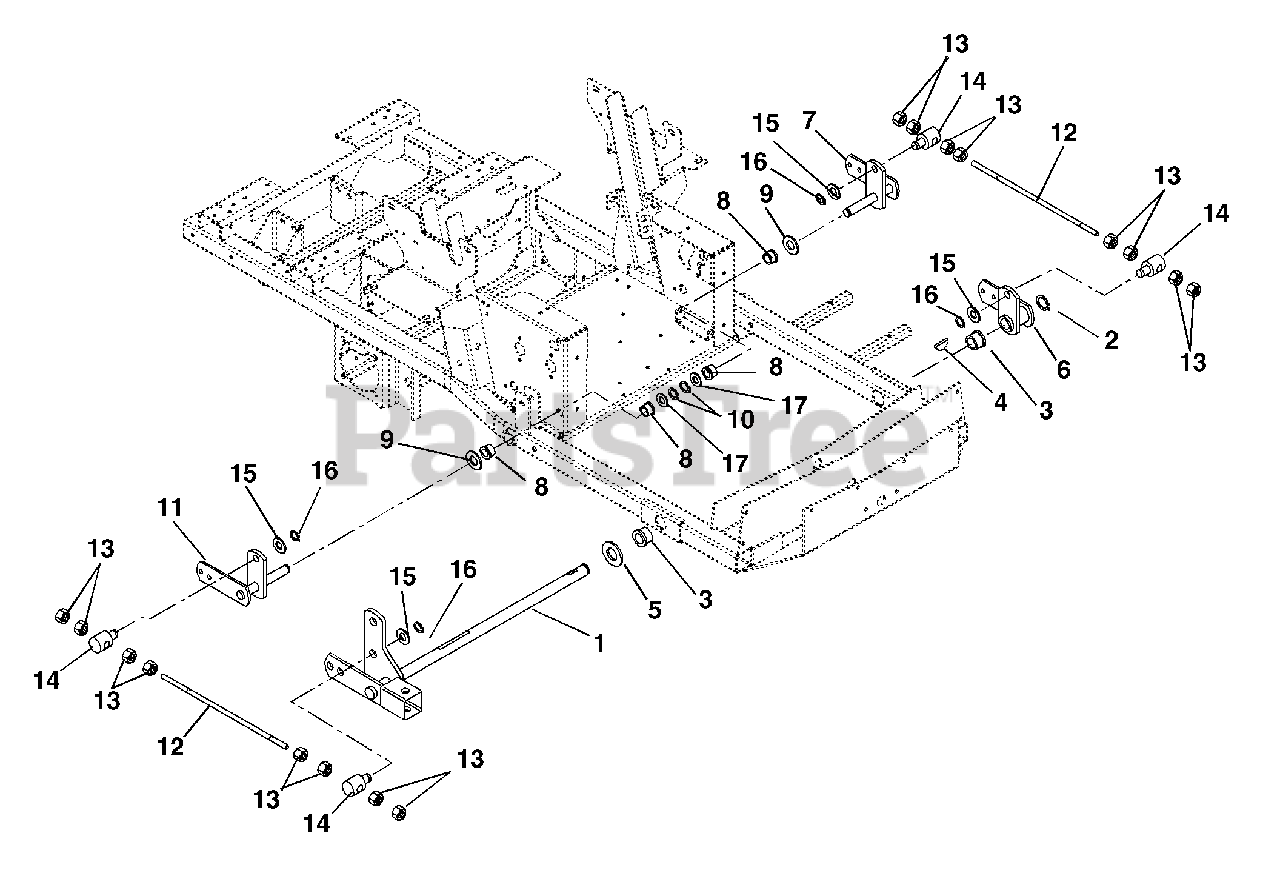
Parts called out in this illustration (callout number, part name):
1	Lift, Mower
2	Ring, Retaining External 1.00 x .078
3	Bushing, Flange Nylon 1.02 x 1.385 x .75 x 1.75
4	Key, Woodruff .25 x 1.00
5	Washer, Flat Steel 1.063 x 2.00 x .134
6	Weldment, Lift Arm-Front
7	Weldment, Rear Lift Arm-Left Hand
8	Bushing, Flange Nylon .762 x 1.0 x .58 x 1.48
9	Washer, Hardened Steel .758 x 1.23 x .031
10	Ring-Retaining-External .689 x .077
11	Weldment, Rear Lift Arm- Right Hand
12	Rod-Lift Assist
13	Nut-Jam .50-13
14	Pivot-Mower Lift
15	Washer-Flat-Steel .630 x 1.005 x .062
16	Ring-Retaining-External .625 x 05
17	Washer-Flat-Steel .755 x 1.25 x .125
